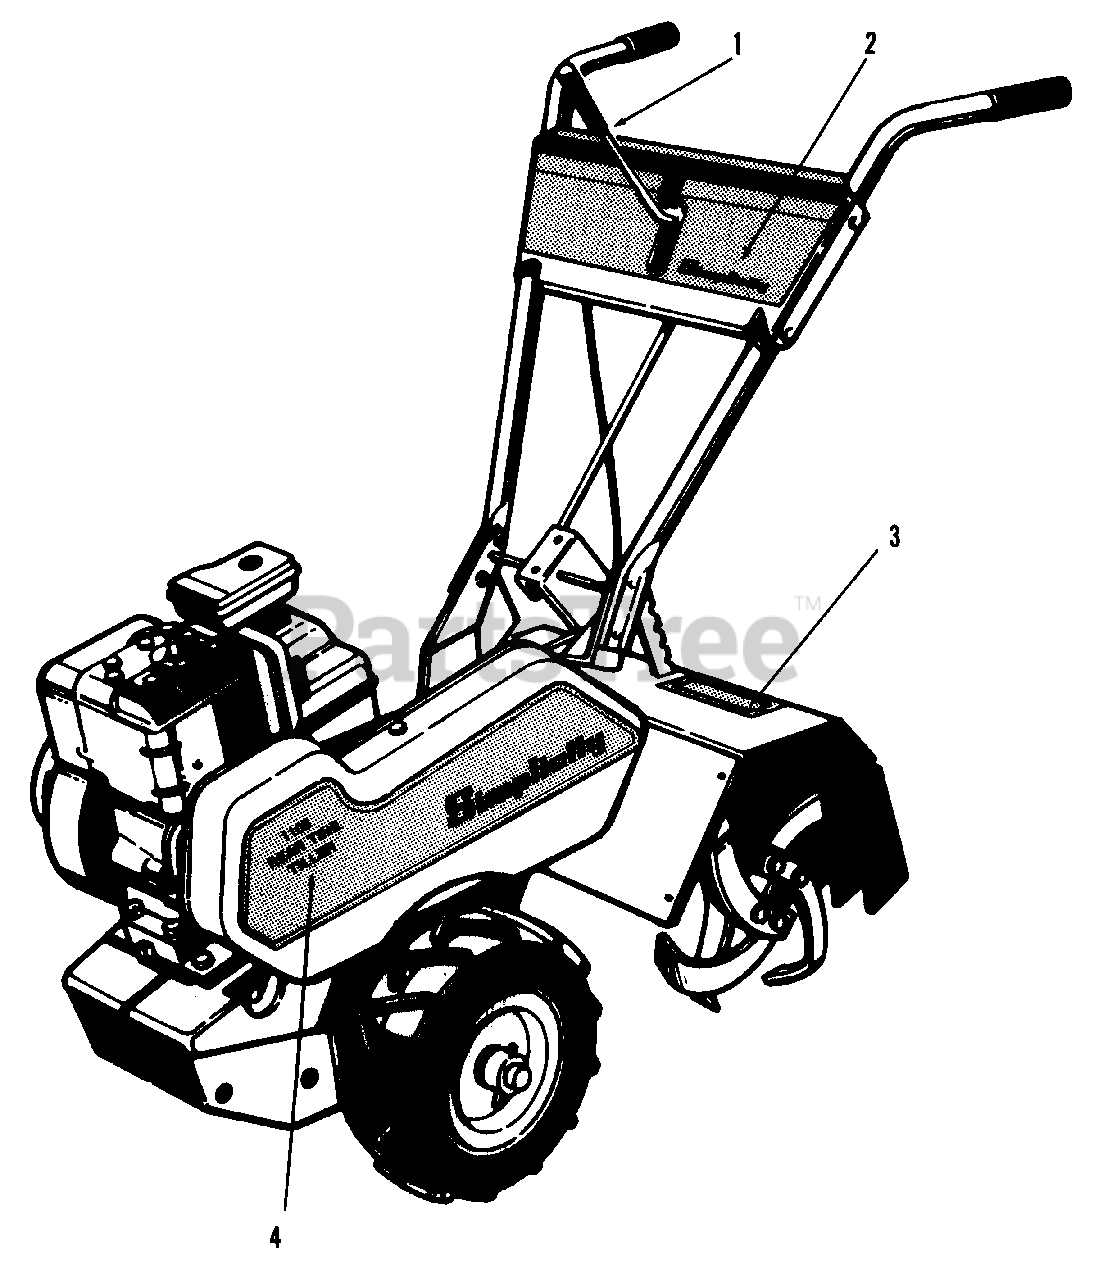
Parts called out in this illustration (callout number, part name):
1	DECAL, Throttle Control
2	DECAL, Shift Panel
3	DECAL, Tine Shield
4	DECAL, Belt Guard
